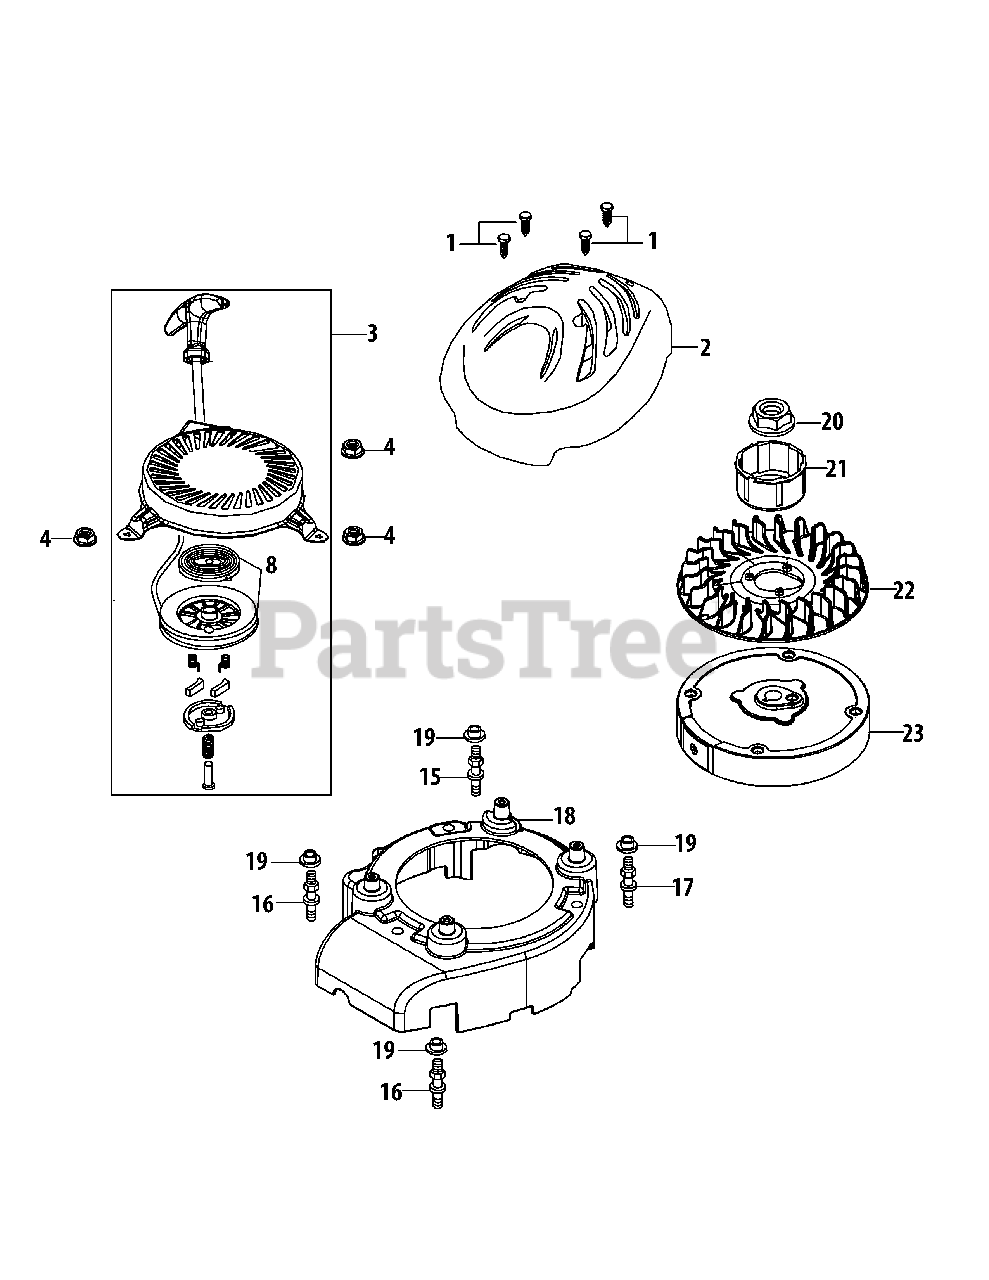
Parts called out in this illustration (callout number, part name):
1	Self-Tapping Bolt, Hilo #12-16 X 1.00"
2	Outer Shroud (Application Specific)
3	Recoil Starter Assembly
4	Nut M6X10Mm Starter/Carb/Muff
8	Starter Pulley
15	Shroud Stud Left/Black
16	Shroud Stud Front/Unmarked
17	Shroud Stud Right/White
18	Inner Shroud
19	Engine Shroud Spacer
20	Flywheel Nut M14
21	Starter Cup
22	Cooling Fan
23	Flywheel
